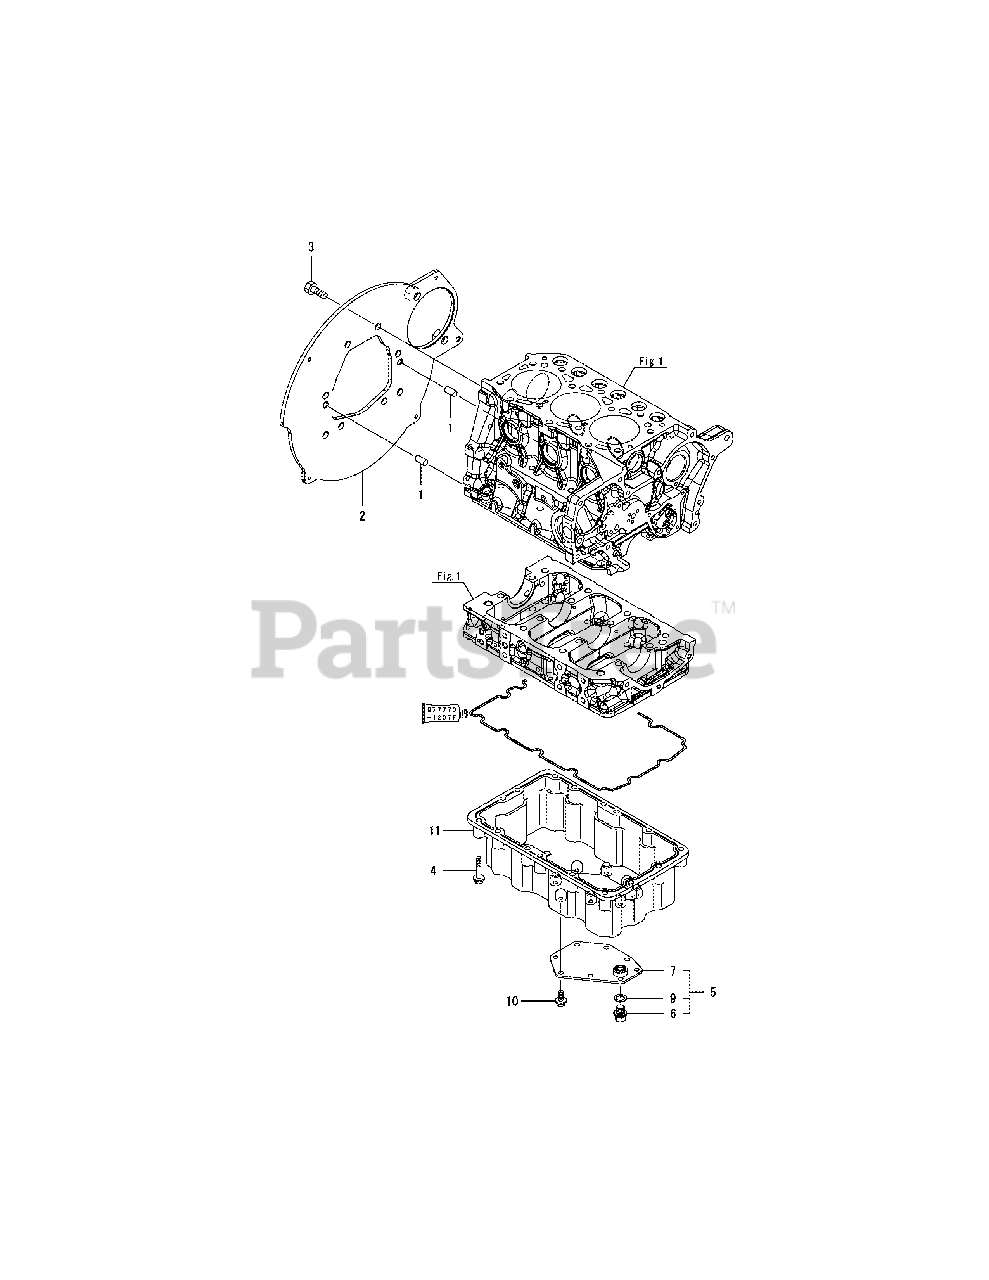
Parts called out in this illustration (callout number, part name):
4	BOLT M 6X 35 PLATED
5	COVER CMP, OIL SUMP
7	COVER, OIL SUMP
9	SEAL WASHER 12
10	BOLT M 6X 14 PLATED
